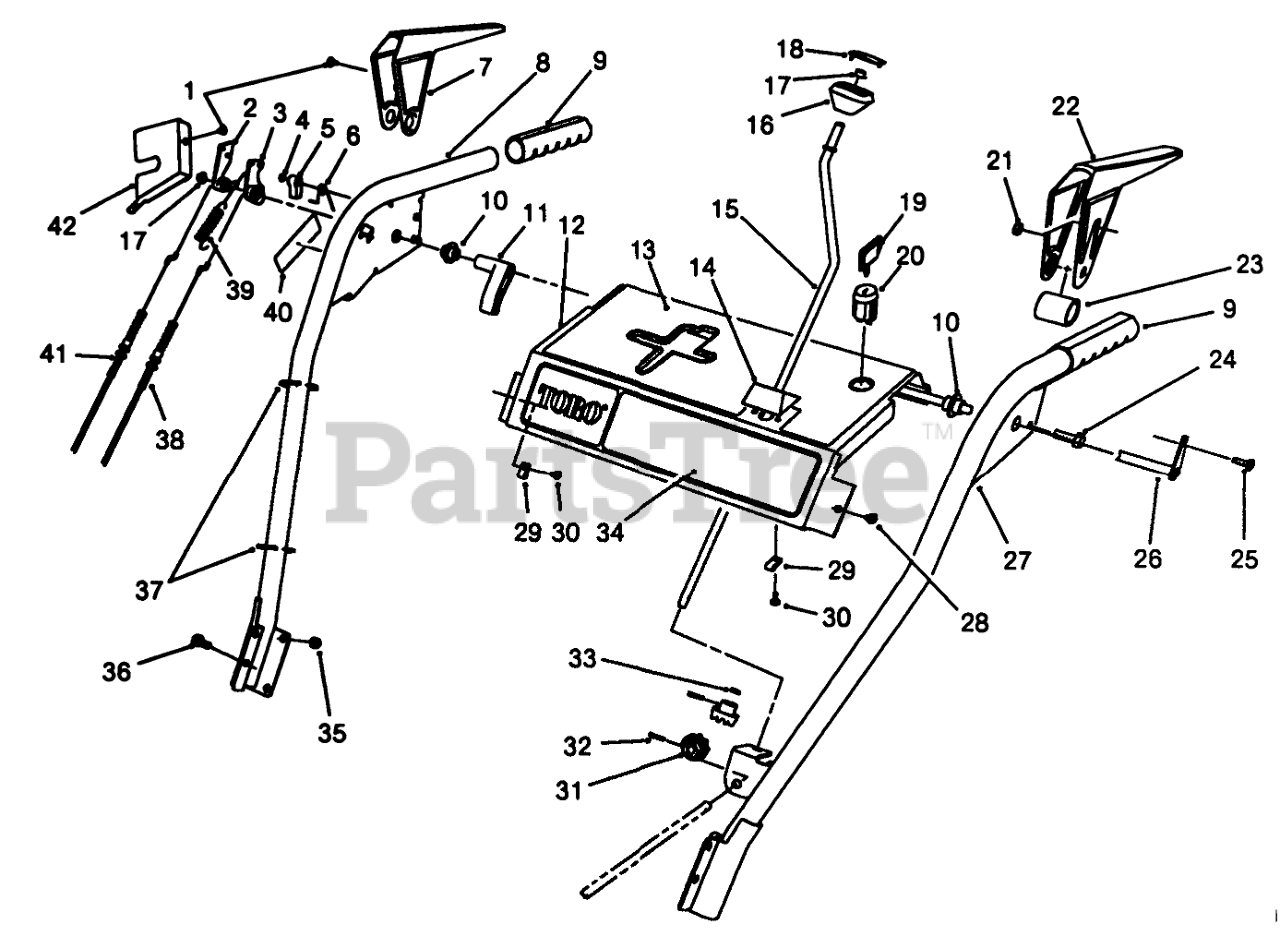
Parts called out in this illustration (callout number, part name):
1	SCREW-HH
2	TANG-LOCKING
3	CAM-RELEASE
4	E-RING-RETAINER
5	LATCH-LOCKING
6	SPRING-TORSION
7	Lever-Impeller
8	Handle-RH
9	HANDLE GRIP
10	BUSHING-LEVER
11	LEVER-TRIP
12	Panel-Control
13	Decal-Panel, Top
14	PLATE-GUIDE
15	CRANK-ROD, CHUTE
16	KNOB-CONTROL, CHUTE
17	RETAINER-PUSH ON
18	COVER-KNOB
19	KEY-IGNITION
20	SWITCH
21	NUT-LOCK, NI
22	Lever-Traction
23	SPACER-LEVER, TRACTION
24	SCREW-HHF
25	SCREW-HWH
26	CROSS ROD ASM
27	LH HANDLE WA (24")B
28	SCREW-HWHTF
29	R CLAMP
30	SCREW-PPH
31	GEAR-UNIVERSAL
32	PIN-SPRING
33	WASHER-RUBBER
34	DECAL-FRONT PANEL
35	NUT-LOCK, NI
36	SCREW-HHF
37	TIE-CABLE
38	CABLE-TRACTION
39	Spring-Extension
40	Decal-Warning
41	CABLE-IMPELLER
42	Cover Lever Lock
